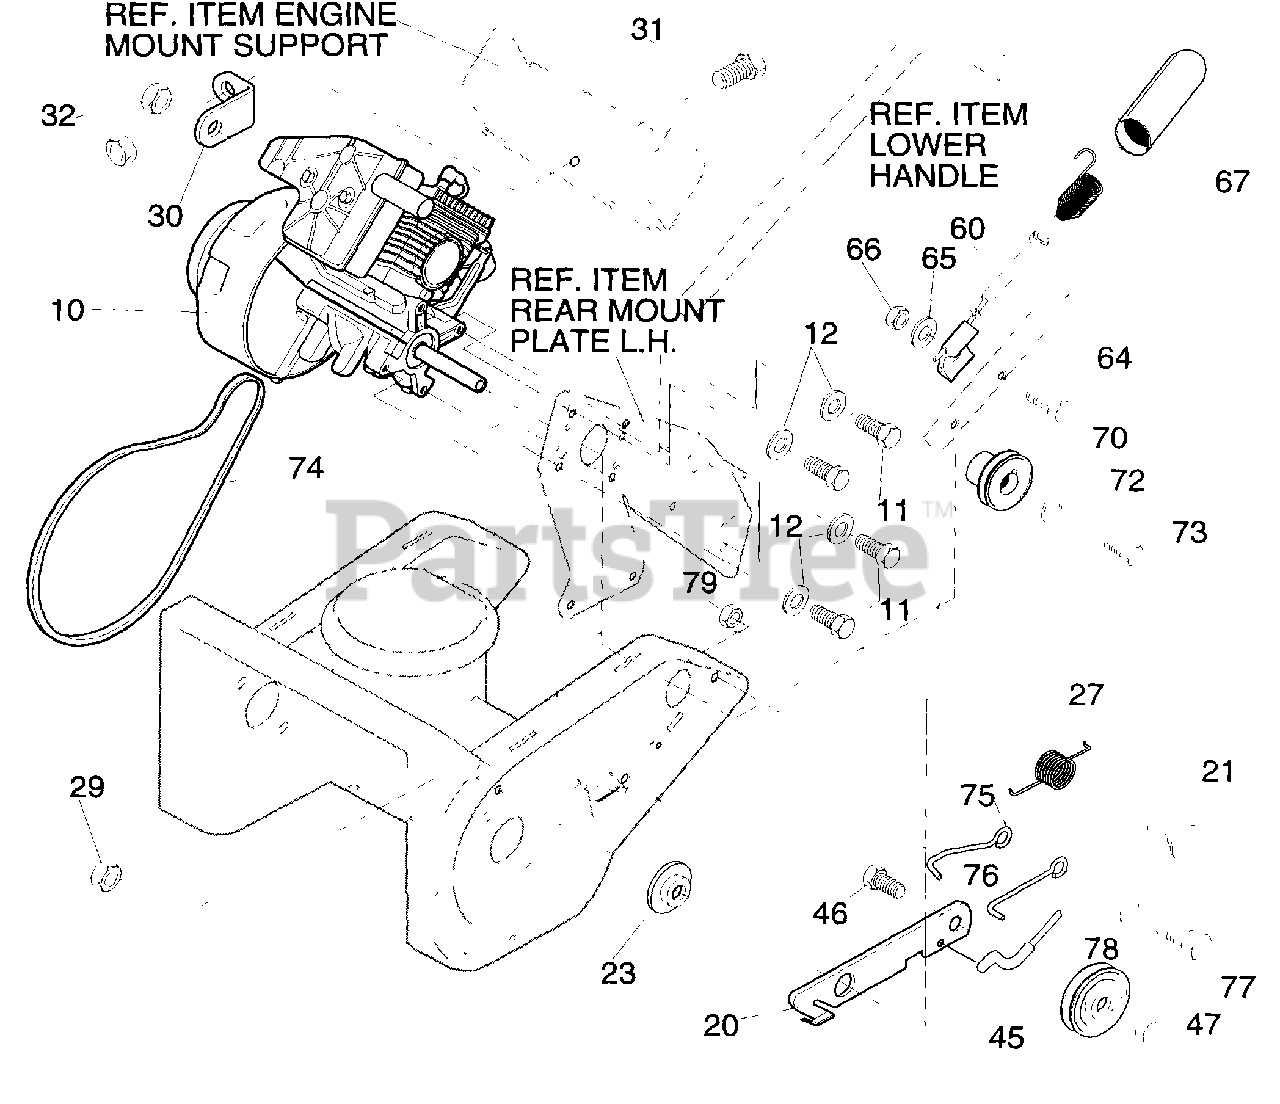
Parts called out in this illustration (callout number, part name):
10	5HP 2CY
11	SCREW, 5/16-18 X .75 HMC
12	WASHER, HVSPTLK
20	BRKT, IDLER ARM
21	BOLT, IDLER ARM
23	SPACER, .38 X 1.25 X .324
27	SPRING,TORSION,BRAKE
29	NUT, 3/8-16 HXCTRLKJAM
30	SUPPORT, ENGINE
31	SCREW, 5/16-18 X .50 HHC
32	NUT, 5/16-18 REGHEXCTRLK
45	PULLEY, IDLER 1.88 X .5 X .38
46	BOLT, 3/8-16 X 1.25 SPCARR
47	NUT, 3/8-16 HXCTRLKJAM
60	CABLE, DRIVE CONTROL
64	SCREW, 1/4-20 X 1.50 HHC
65	FLATWASHER .281 X .63 X .065
66	NUT, 1/4-20 REGHEXCTRLK
67	COVER, CABLE SPRING
70	PULLEY HALF, 3L 2.00
72	FLATWASHER .333 X .87 X .119
73	SCREW, 5/16-24X .88
74	BELT, V3L X 35, .048 D
75	GUIDE, BELT .38 ID X 2.66
76	GUIDE, BELT .38 ID X 3.30 OFF
77	SCREW, 3/8-16 X 1.00 HMC
78	FLATWASHER .406 X .81 X .065
79	NUT, 3/8-16 REGHXCTRLK
